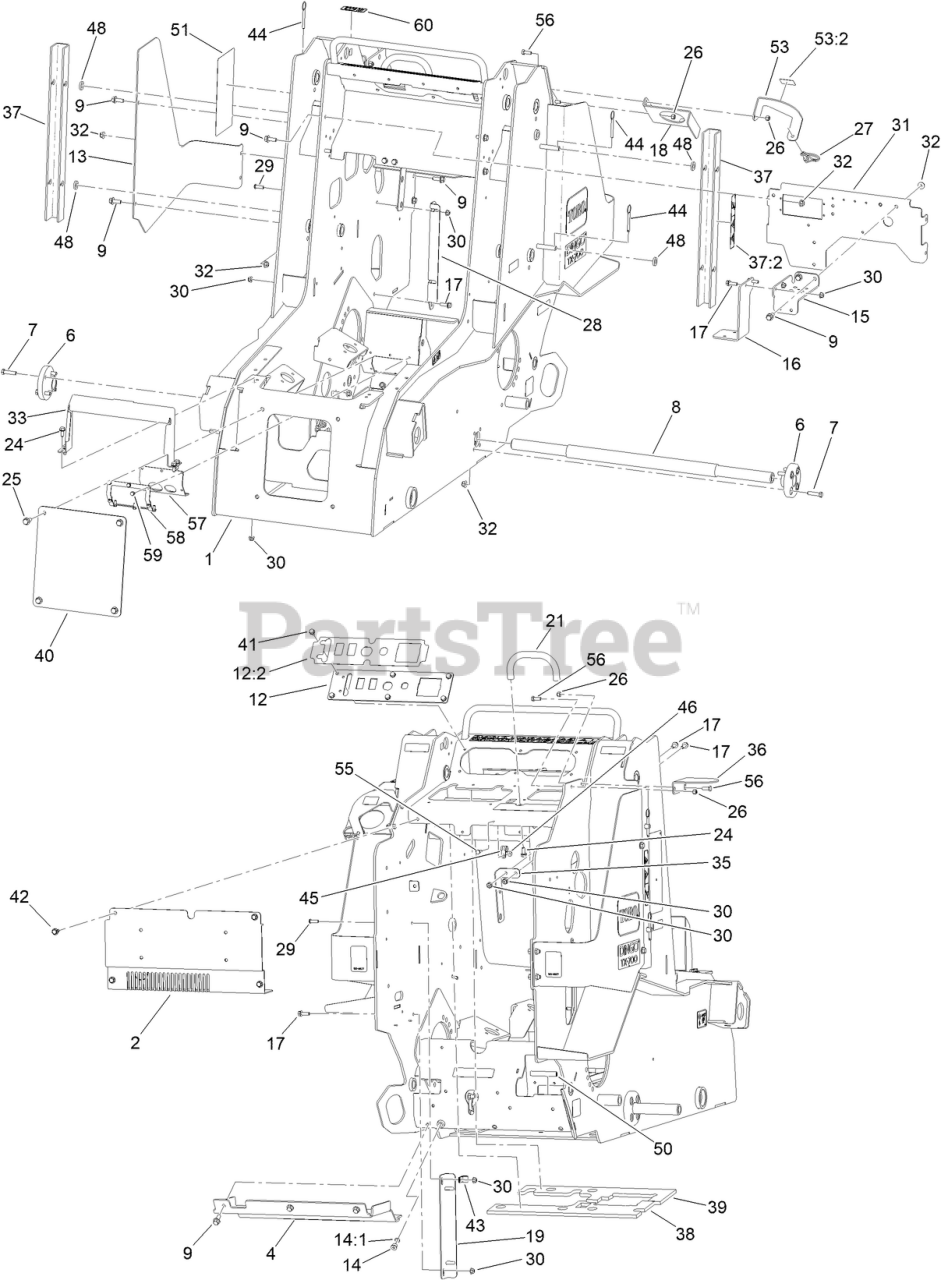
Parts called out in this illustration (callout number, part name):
1	MAIN FRAME ASM
2	AIR BOX [BLACK]
4	PLATE-BOTTOM, FRAME
6	HUB-SHAFT
7	SCREW-HH
8	SHAFT-TRACK
9	SCREW-HHF
12	PLATE-CONSOLE
12:2	DECAL-CONTROLS
13	WRAP-TANK, RH
14	PLUG-HEX, HOLLOW
14:1	O-RING
15	BRACKET-TANK
16	BRACKET-TANK
17	SCREW-HHF
18	BRACKET-FUEL
21	BAR-REFERENCE
24	SCREW-HHF
25	SCREW-HHF
26	NUT-LOCK, NI
27	PIN-LYNCH
29	SCREW-HSBH
30	NUT-HF, NI
31	PLATE-CONSOLE COVER, FRONT
32	NUT-HF, NI
33	STRAP-HOOD
35	BRACKET-TANK
36	CAP-COVER
37	ARM-LOCKING
37:2	DECAL-DANGER
38	FOAM-HEAT SHIELD
39	FOAM-HEAT SHIELD
40	COVER-FRONT
41	SCREW-HWH
42	SCREW-TAPPING
43	CLAMP-R
44	PIN-COTTERLESS
45	CLAMP-R
46	NUT-HF
48	WASHER-NEOPRENE
51	DECAL-SERVICE
53	PLATE-LOCK, FUEL CAP, RH
53:2	DECAL-ULTRA LOW SULFUR DIESEL
55	SCREW-HH
56	SCREW-HH
57	AIR - GUARD
58	RETAINING - RING
59	SCREW-HWH
60	DECAL-HYD FLUID
